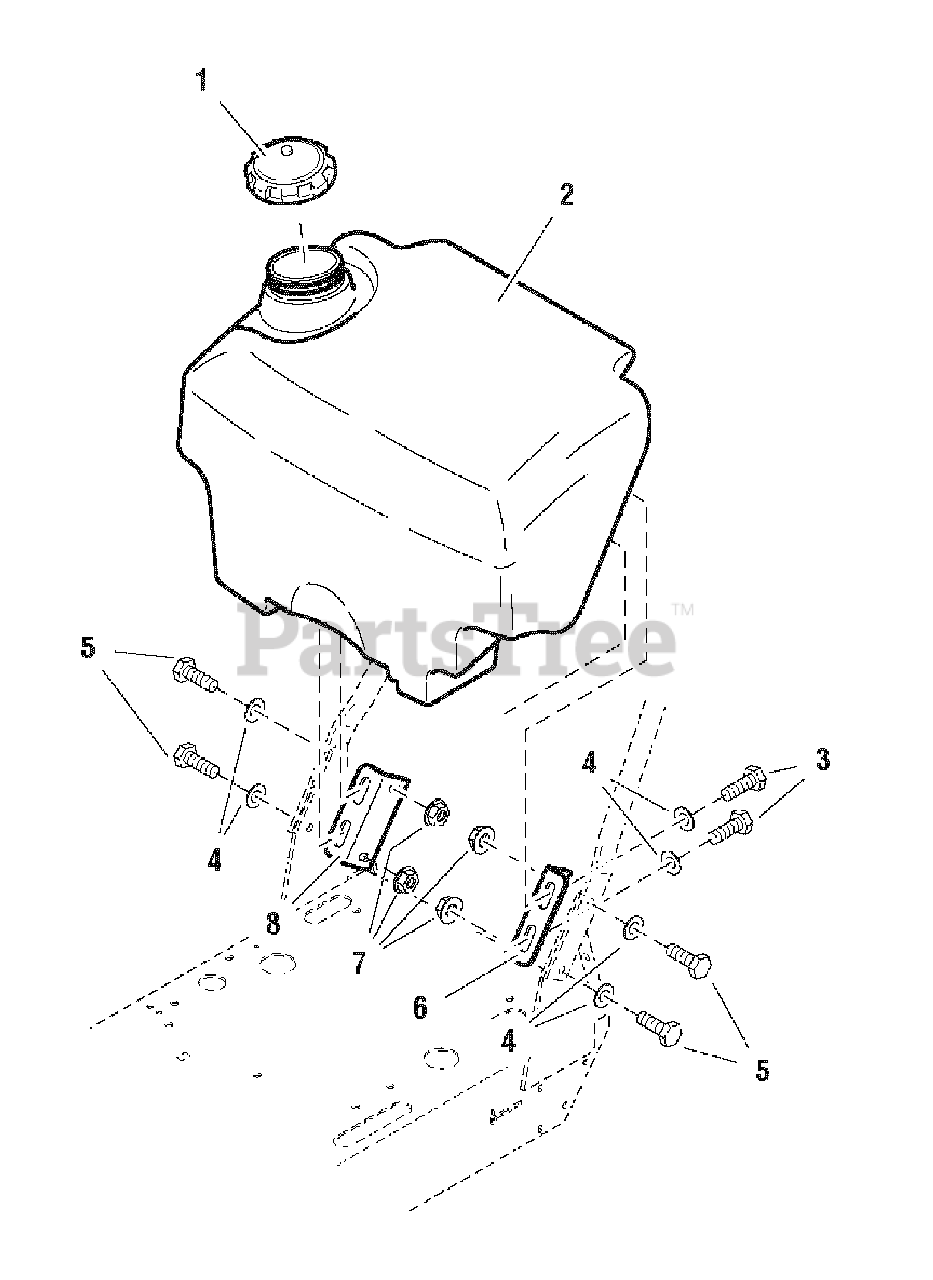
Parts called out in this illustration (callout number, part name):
1	FUEL TANK CAP
2	FUEL TANK
3	BOLT, 3/8-16 X 3/4" GD5 CZ
4	WASHER, 3/8
5	BOLT, 3/8-16 X 1-1/4" GD5 CZ
6	FUEL TANK MOUNT - LH
7	NUT, Hex Serrated Flange, 3/8-16
8	FUEL TANK MOUNT - RH
